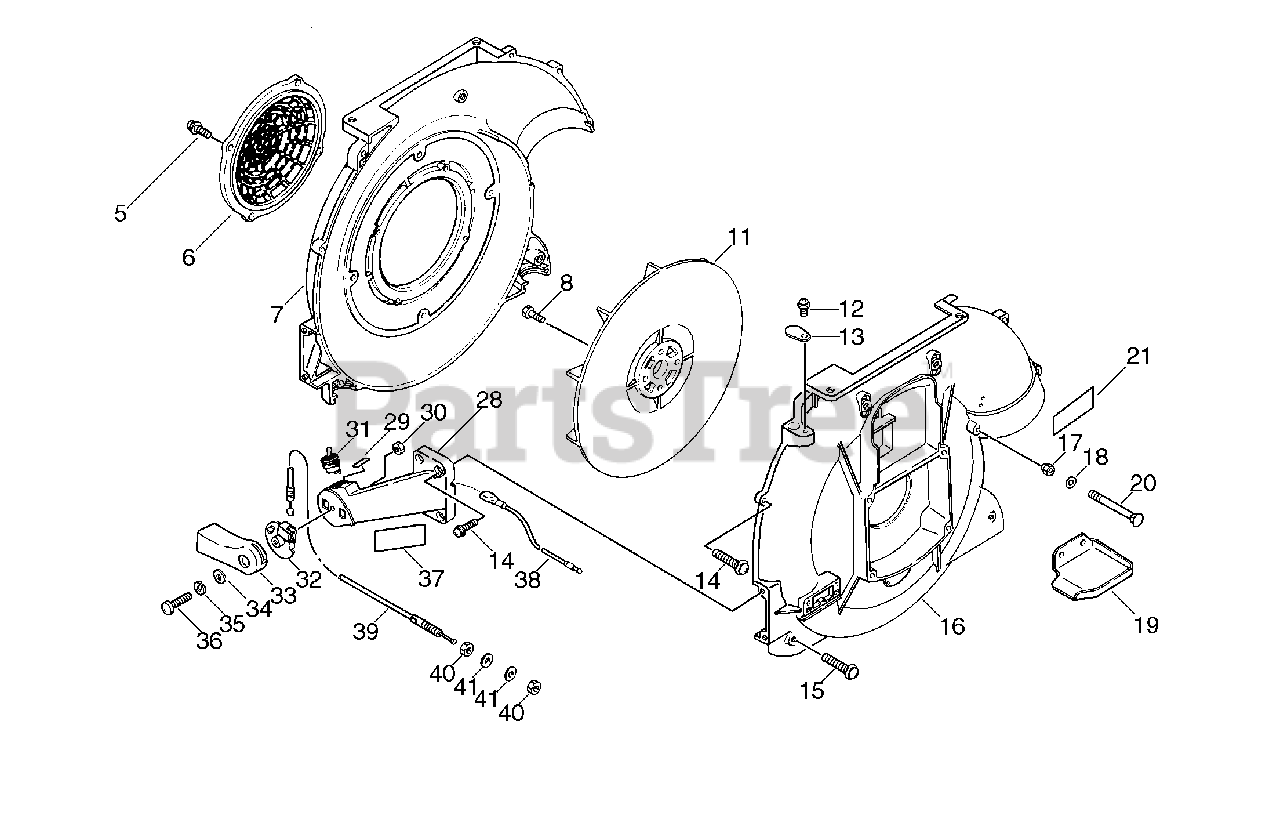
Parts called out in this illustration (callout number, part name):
5	BOLT - 6X14
6	GUARD, DEBRIS
7	COVER, FAN - INNER -- ORANGE
8	BOLT - 5X16
12	SCREW - 5X10
14	SCREW - 5X20
15	SCREW - 5X25
16	COVER, FAN - OUTER
17	NUT - 5 -- CAP
18	WASHER - 5
19	BRACKET, MUFFLER COVER
20	BOLT, ELBOW
21	LABEL - NOISE
28	MOUNT, THROTTLE LEVER
29	LABEL - STOP
30	LOCKNUT - 6
31	IGNITION SWITCH ASSY
33	TRIGGER, THROTTLE
34	WASHER - 6
35	LOCKWASHER - 6
36	SCREW - 6X25
37	LABEL - CAUTION
39	CABLE, THROTTLE
41	WASHER - 6
